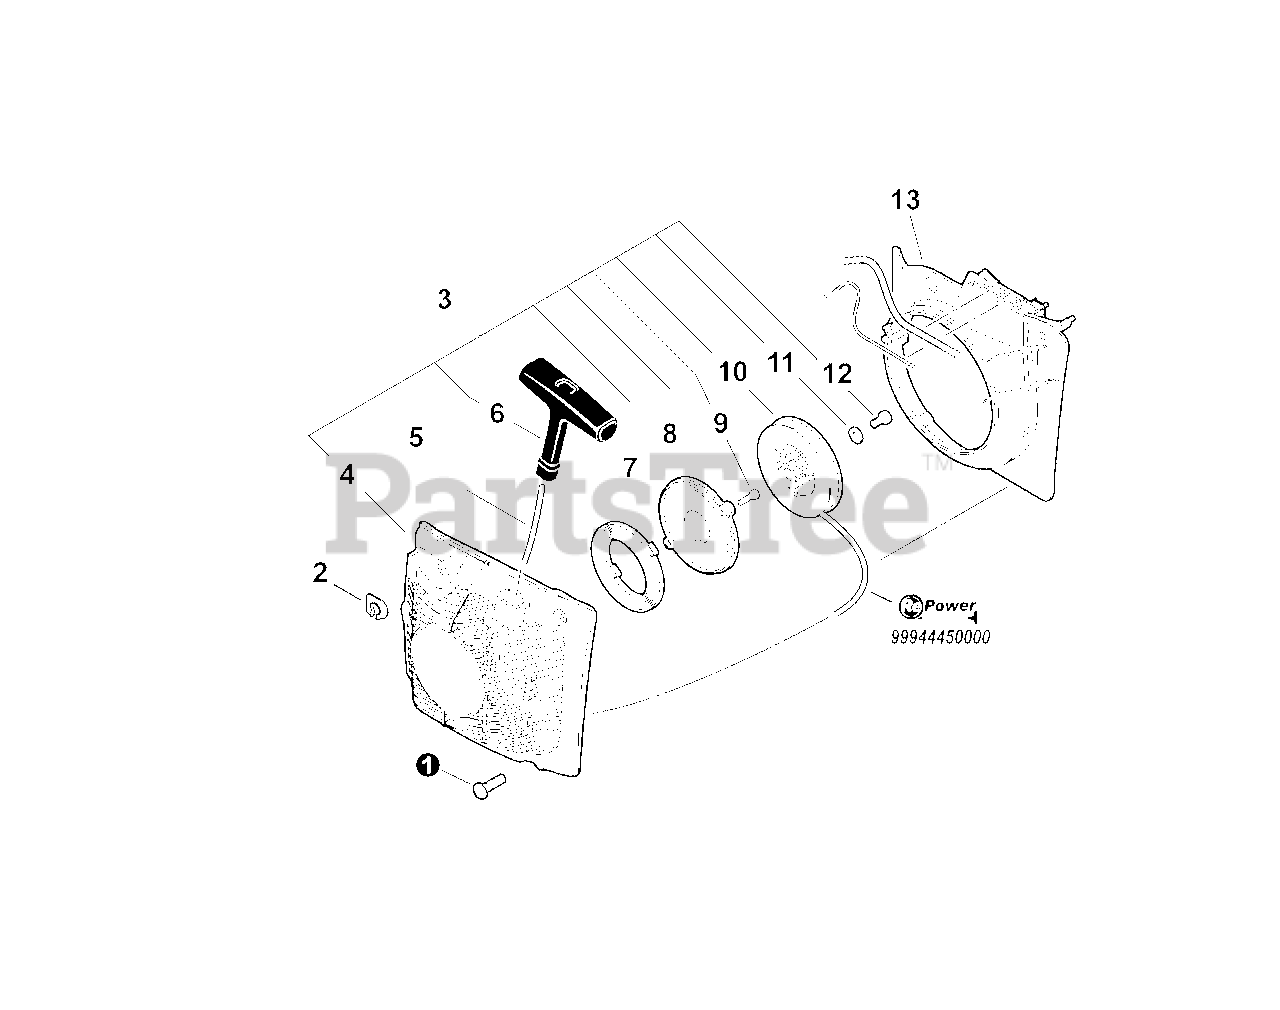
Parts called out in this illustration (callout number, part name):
1	BOLT, TORX 5×20
2	PLATE, EYE
3	STARTER ASSY, RECOIL
4	CASE, STARTER
5	ROPE, STARTER Ø4×950
6	GRIP, STARTER
7	SPRING, RECOIL
8	PLATE, STARTER
9	BOLT, TORX 4×12
10	REEL, ROPE
11	WASHER 5.2×16×1.0
12	BOLT, TORX 5×10
13	COVER, FAN
